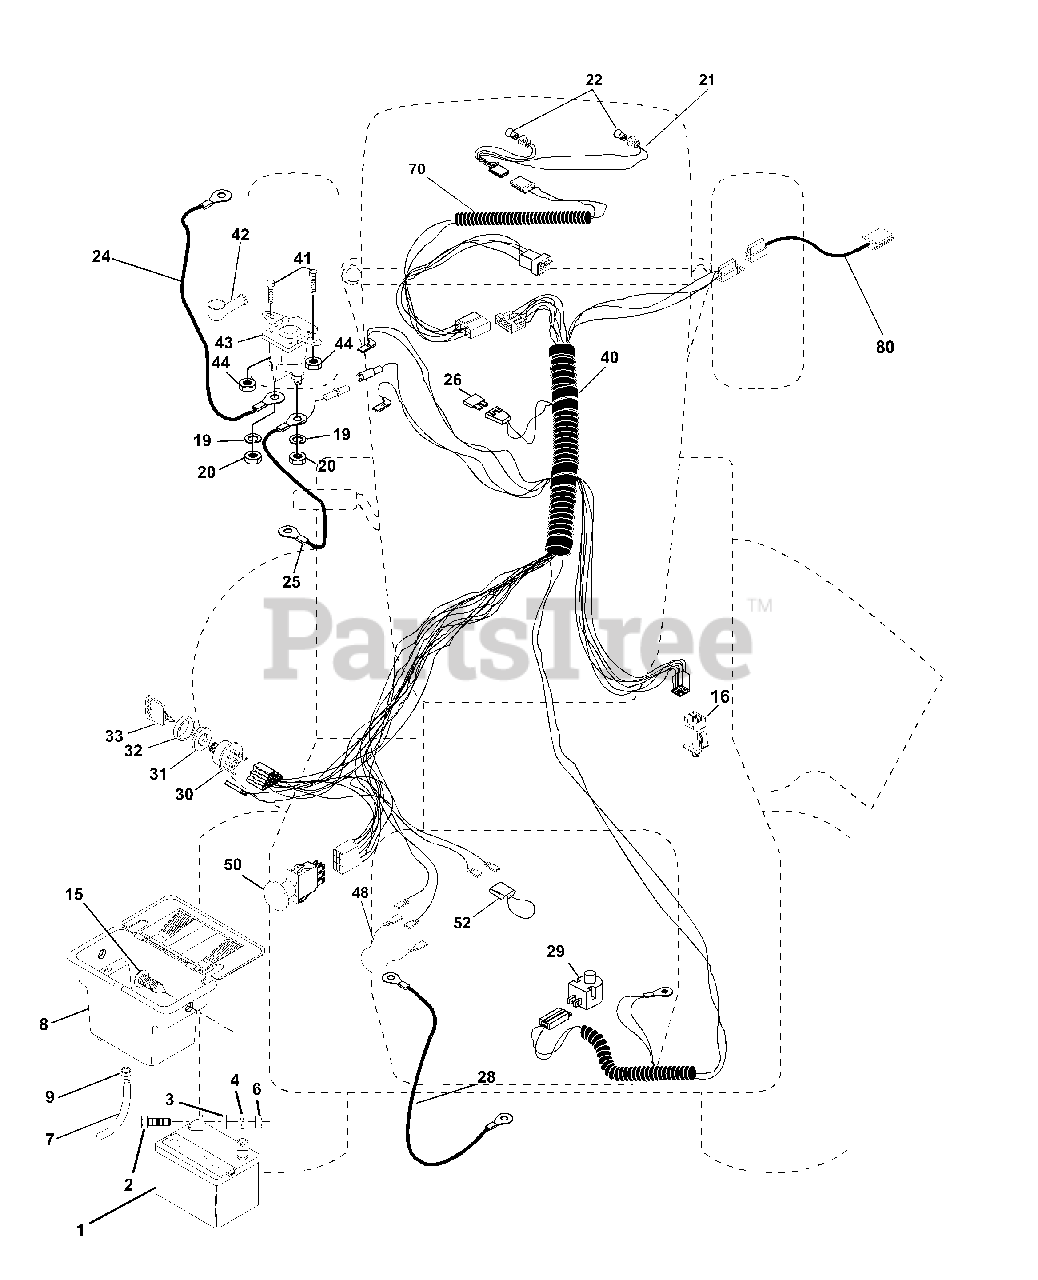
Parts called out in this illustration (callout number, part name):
1	Battery 12 Volt 25 AMP
2	Bolt Hex Hd 1/4-20unc X 3/4
3	Washer 9/32 X 5/8 X 16 Ga.
4	Washer Lock Hvy Helical 1/4
6	Nut Fin Hex 1/4-20 Unc
7	Tube Plastic 12"
8	Case Battery w/2 Holes W BRTY
9	Clamp Hose Olive
15	Fastener Snap-In
16	Switch Interlock Push-In
19	Washer Lock 1/4
20	Nut Jam Hex 1/4-20 Unc
21	Harness Asm Light W/4152j
22	Bulb Light #1156
24	Cable Battery 6 Ga 11" red
25	Cable Battery 6 Ga 44" w/16W
26	Fuse 30 AMP Auto Green
28	Cable Ground 6 Ga 12" black
29	Switch Plunger Nc Gray
30	Switch Ign 4 pos w/lights
31	Nut Ignition
32	Cover Sw Ignition
33	Key Ign Modleded Generic
40	Harness Ignition
41	Bolt Blk Fin Hex 1/4 - 20 x 1/2
42	Cover Terminal Red
43	Solenoid
44	Nut Keps Hex 1/4-20 Unc
48	Adapter Ammeter Rectangular
50	Switch PTO 3 PTD Black
52	Protection Wire Loop
70	Harness, Eng.
80	Harness Clutch EVX
